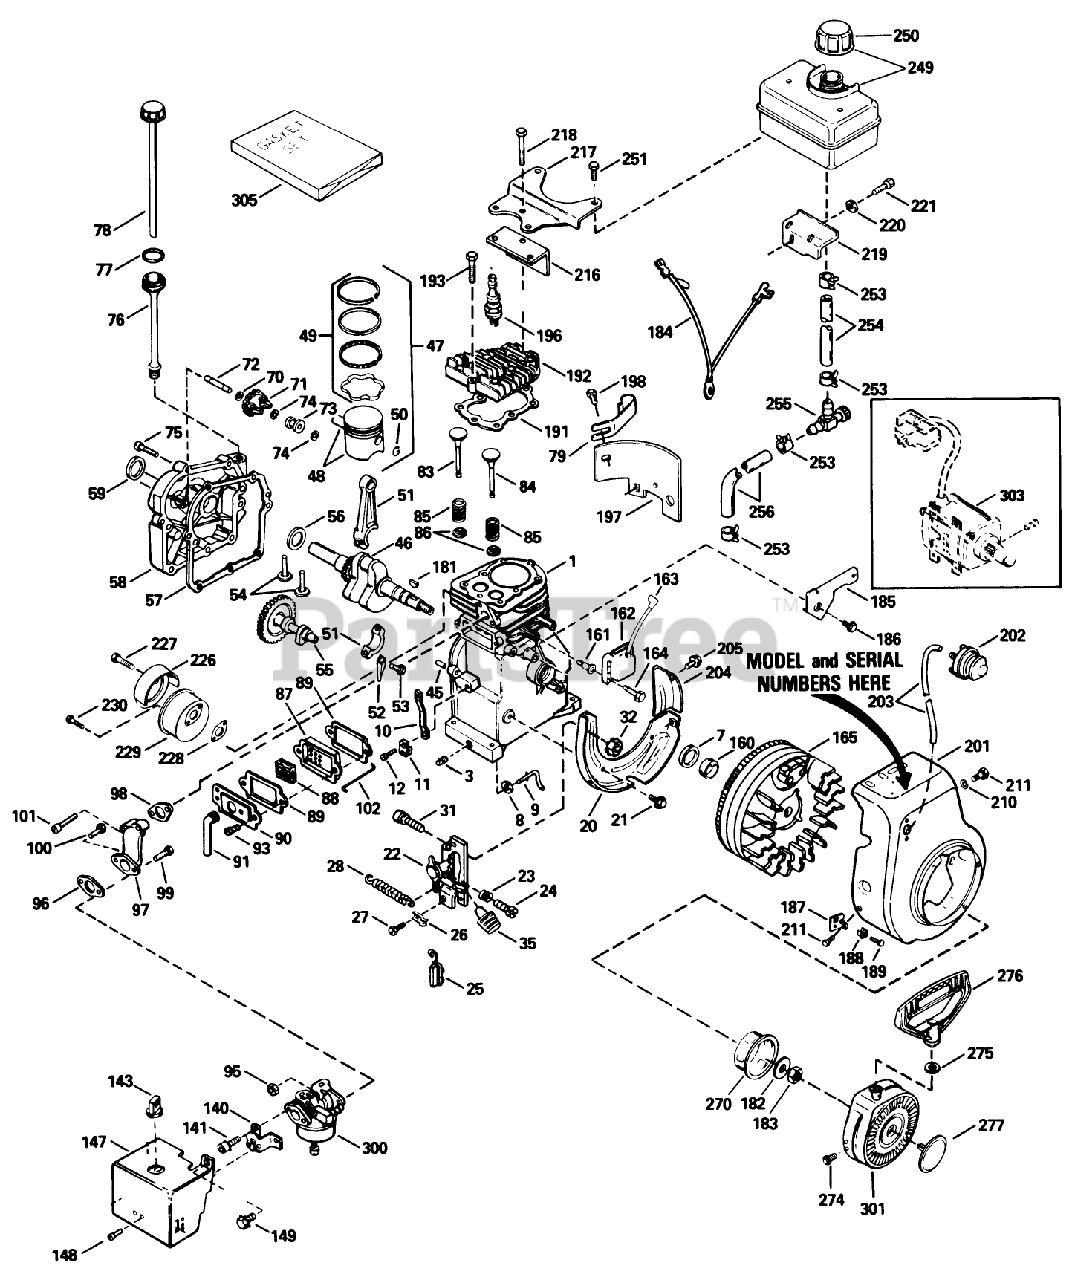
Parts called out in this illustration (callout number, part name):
1	Cylinder Assembly (Incl. Ref. #2, 3 35)
3	Plug-Drain, Oil (SQH 1/4-18)
7	Seal-Oil
8	Washer-Flat
9	Rod-Governor
10	Lever-Governor
11	Clamp-Lever, Governor
12	Screw
20	Baffle-Blower Housing
21	Screw (1/4-20x19/32)
22	Control Assembly, Speed (Incl. Ref. #155 thru 158 160)
23	Spring-Compression
24	Screw
25	Terminal
26	Conduit
27	Screw (10-32 x 3/8)
28	Spring-Extension
31	Screw
32	Nut-Lock
35	Knob-Control
45	Pin-Dowel
46	Crankshaft
47	Piston-Pin Ring Assy. (Std.)(Incl. Ref. #14A, 15 16)
47	Piston-Pin Ring Assy. (.010 oversize)(Incl. Ref. #14A, 15 16)
47	Piston-Pin Ring Assy. (.020 oversize)(Incl. Ref. #14A, 15 16)
48	Piston Pin Assy. (Std)(Incl. Ref. #16)
48	Piston Pin Assy. (.010 oversize) (Incl. Ref. #16)
48	Piston Pin Assy. (.020 oversize) (Incl. Ref. #16)
49	Piston Ring Set Std.
49	Piston Ring Set .010 O.S.
49	Piston Ring Set .020 O.S.
50	Ring-Retaining, Piston Pin
51	Rod Assembly, Connecting (Incl. Nos. 17 18)
52	Dipper-Oil
53	Bolt-Rod, Connecting
54	Lifter-Valve
55	Camshaft (Compression Release)
56	Washer-Thrust
57	Gasket-Cylinder Cover
58	Cover-Cylinder (Incl. Ref. #59 72)
59	Seal-Oil
70	Washer-Flat
71	Governor Gear ASM
72	Shaft-Governor
73	Spool-Governor
74	Ring-Retaining
75	Screw (1/4-20 x 1-1/4)
76	Tube-Fill, Oil
77	O-Ring
78	Dipstick
79	Clip-Tube, Fill
83	Valve, Exhaust (Std.)(Incl. No. 40)
83	Valve, Intake (1/32" oversize)(Incl. No. 40)
84	Valve, Intake (Std.) (Incl. Ref. #40)
84	Valve, Intake (1/32" oversize)(Incl. No. 40)
85	Spring-Valve
86	Cap-Valve, Spring
87	Body-Breather
88	Element-Breather
89	Gasket-Breather
90	Cover-Breather
91	Tube-Breather
93	Screw
95	Nut and Lock Washer (1/4-28)
96	Gasket
97	Pipe-Intake (Incl. Ref. #47)
98	Gasket-Intake
100	Screw-Hex Hd.
101	Screw (1/4-20 x 1-19/32)
102	Jet-Main
140	Bracket-Choke
141	Screw (10-32 x 1/2)
143	Knob-Choke
147	Cover-Carburetor
148	Screw (8-32 X 5/16)
149	Screw (10-32x1/2)
160	Spacer
162	Solid State
163	Cover-Spark Plug
164	Screw
165	CLAMP
181	Key-Flywheel
182	Washer-Belleville
183	Nut-Flywheel
184	Wire-Ground
185	Bracket-Hold Down
186	Screw (10-24 x 9/16)
187	Bracket
188	Grommet
189	Screw (8-32 x 3/8)
191	Gasket-Cylinder Head
192	Head-Cylinder
193	Screw (5/16-18x1-1/2)
196	Spark Plug-Resistor (R J19 L M)
197	Extension-Blower
198	Screw
201	Housing-Blower
202	Primer-Asm
203	Line-Primer
204	Baffle-Extension
205	Screw-Hex Washer Hd.
210	Washer
211	Screw
216	Baffle-Heat
217	Plate-Fuel Tank
218	Screw (5/16-18 X 2)
219	Bracket-Fuel Tank
220	Washer
221	Screw Assembly
226	Cover-Muffler
227	Screw (1/4-15x7/8)
228	Gasket Exhaust
229	Muffler
230	Screw
249	Tank Assembly-Fuel (Incl. Ref. #250 253)
250	Cap-Fuel
251	Screw (1/4-15x7/8)
253	Clamp-Line, Fuel
254	Line-Fuel (8.62)
255	Valve-Shut Off
256	Line-Fuel
270	Cup-Starter
274	Screw, Hex Hd.
275	Washer
276	Handle-Starter, Mitten Grip
277	Plug Starter
300	Carburetor (Incl. Ref. #87)
301	Rewind Starter
303	Electric Starter Kit 33290C (Optional) Sold as Accessory
305	Gasket Set (Incl. items marked*
